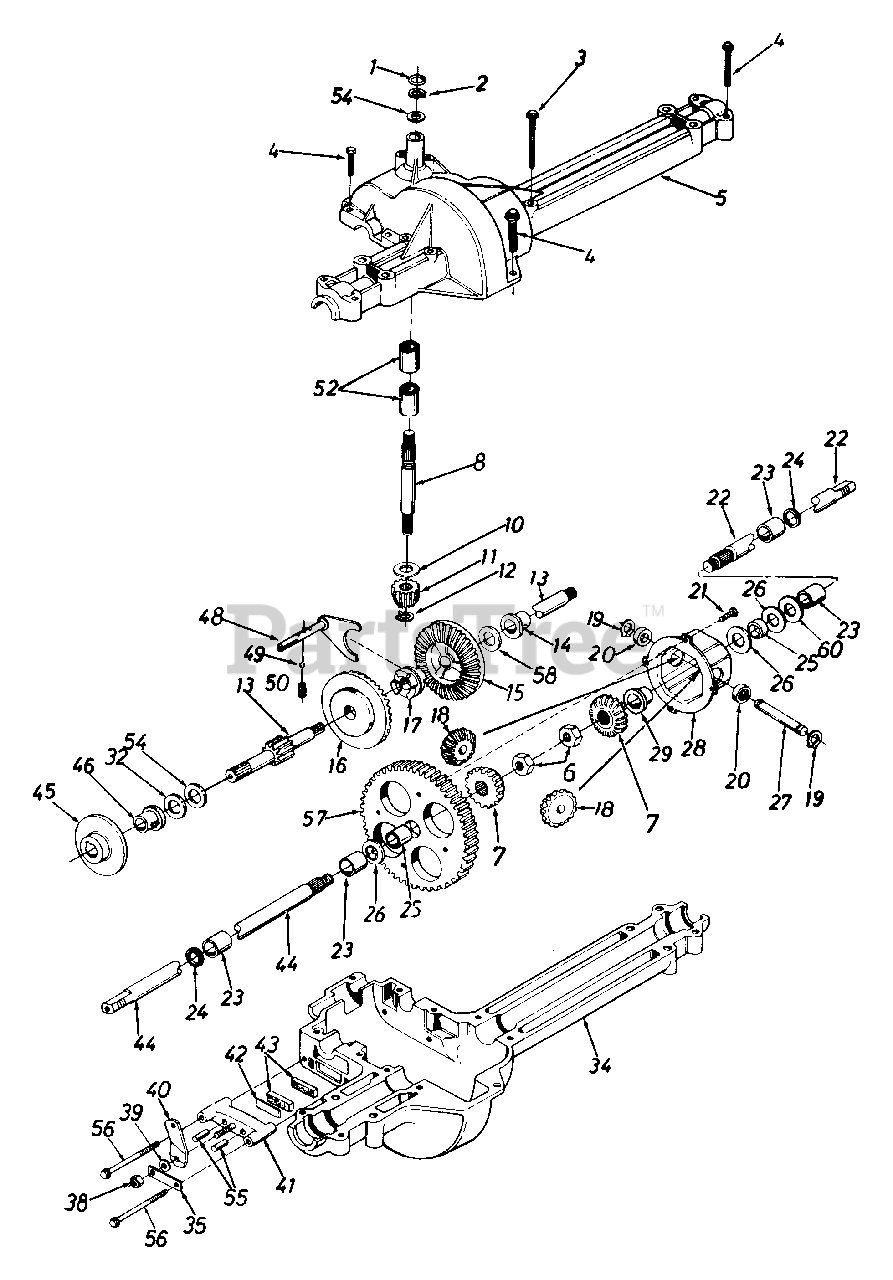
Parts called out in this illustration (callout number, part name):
1	Wire Ring
2	Retaining - Ring
3	Hex Bolt 1/4-20 x 1.75" Lg.
4	Hex Tap Scr. 1/4-20 x 1.25" Lg.
5	Upper Housing
8	Input Shaft
10	Thrust Washer 5/8" I.D. x 1.25" O.D.
11	Pinion Input 14T
12	Retaining Ring
13	Drive Shaft - L.H. Brake
14	Flange Brg. 5/8" I.D. x 3/4" Lg.
15	Bevel Gear 42T Small I.D.
16	Bevel Gear 42T Large I.D.
17	Clutch Collar
18	Miter Gear 15T (H.D.)
19	Retaining Ring
20	Thrust Bearing
21	Pan Head Scr. 1/4-20 x .50" Lg. w/Patch
22	Axle R.H. Ass'y.
23	Sleeve Bearing 3/4" I.D. x 1.0" Lg.
24	Oil Seal 3/4" I.D.
25	Axle Spacer
26	Fl-Wash. .760" I.D. x 1.5" O.D.
27	Cross Shaft
28	Differential Can Ass'y.
32	Washer
32	Thrust Wash. 5/8" I.D. x 1" O.D. x .025" Thk.
32	Fl-Wash. 5/8" I.D. x 1" O.D. x .030" Thk
32	Thrust Wash. 5/8" I.D. x 1" O.D. x .035" Thk.
32	Fl-Wash. 5/8" I.D. x 1" O.D. x .040" Thk
34	Lower Housing
35	Anti-Rotation Brkt.
38	Hex Nut 5/16-24 Thd.
39	Fl-Wash. .344" I.D. x .875" O.D.
40	Actuating Arm
41	Brake Yoke
42	Puck Plate
43	Brake Puck
44	Axle L.H. Ass'y.
45	Brake Disc
46	Flange Bearing 5/8" I.D. x 15/16" Lg.
48	Shift Fork Ass'y.
49	Ball Detent .250" Dia.
50	Spring Detent
52	Needle Brg. 5/8" I.D. x 1/2" Lg.
54	Fl-Wash. 5/8" I.D. x 1" O.D. x .020 Thk.
55	Actuating Pin 5/16" Dia.
56	Hex Wash. Hd. Self-Tap Scr. 1/4-20 Thd.
57	Differential Gear 58T
58	Fl-Wash. 5/8" I.D. x 1" O.D. x .020 Thk.
58	Thrust Wash. 5/8" I.D. x 1" O.D. x .025" Thk.
60	Washer
